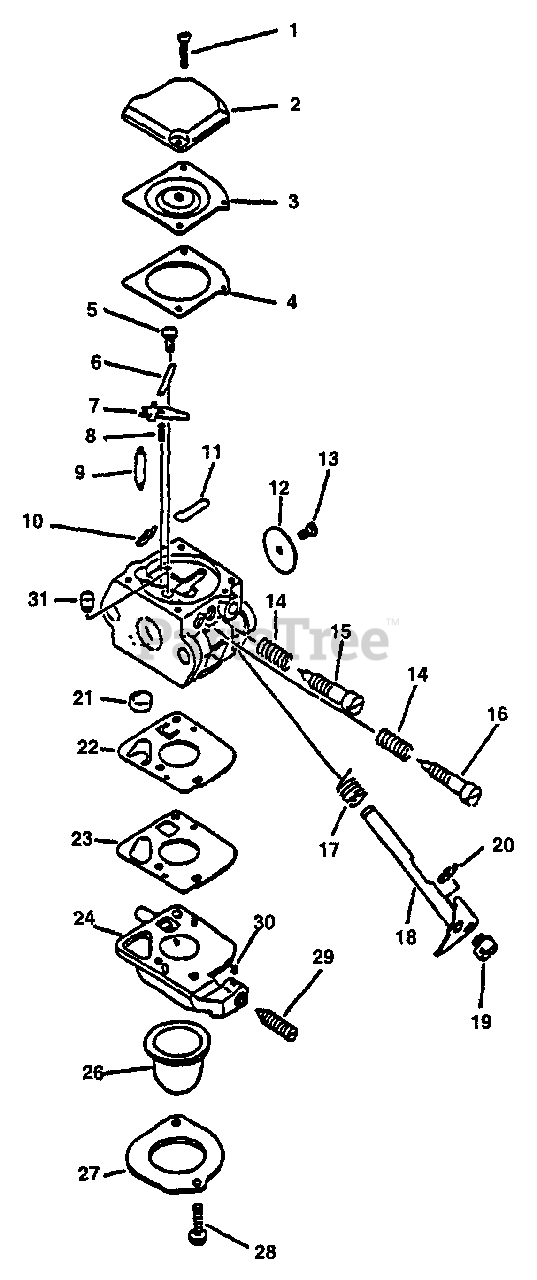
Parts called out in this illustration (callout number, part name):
2	COVER, METERING DIAPHRAGM
3	DIAPHRAGM
4	GASKET, METERING
6	PIN
7	LEVER, METERING
8	SPRING
9	VALVE, NEEDLE
11	PLUG, WELCH
12	VALVE, THROTTLE
14	SPRING, NEEDLE
15	NEEDLE, LOW SPEED
16	NEEDLE, HIGH SPEED
17	SPRING, THROTTLE RETURN
18	SHAFT, THROTTLE
21	STRAINER
24	BODY ASSY, PURGE
26	BULB, PURGE
27	RETAINER
29	SCREW, IDLE ADJUST
30	PIECE, FRICTION
31	NOZZLE, CHECK VALVE
